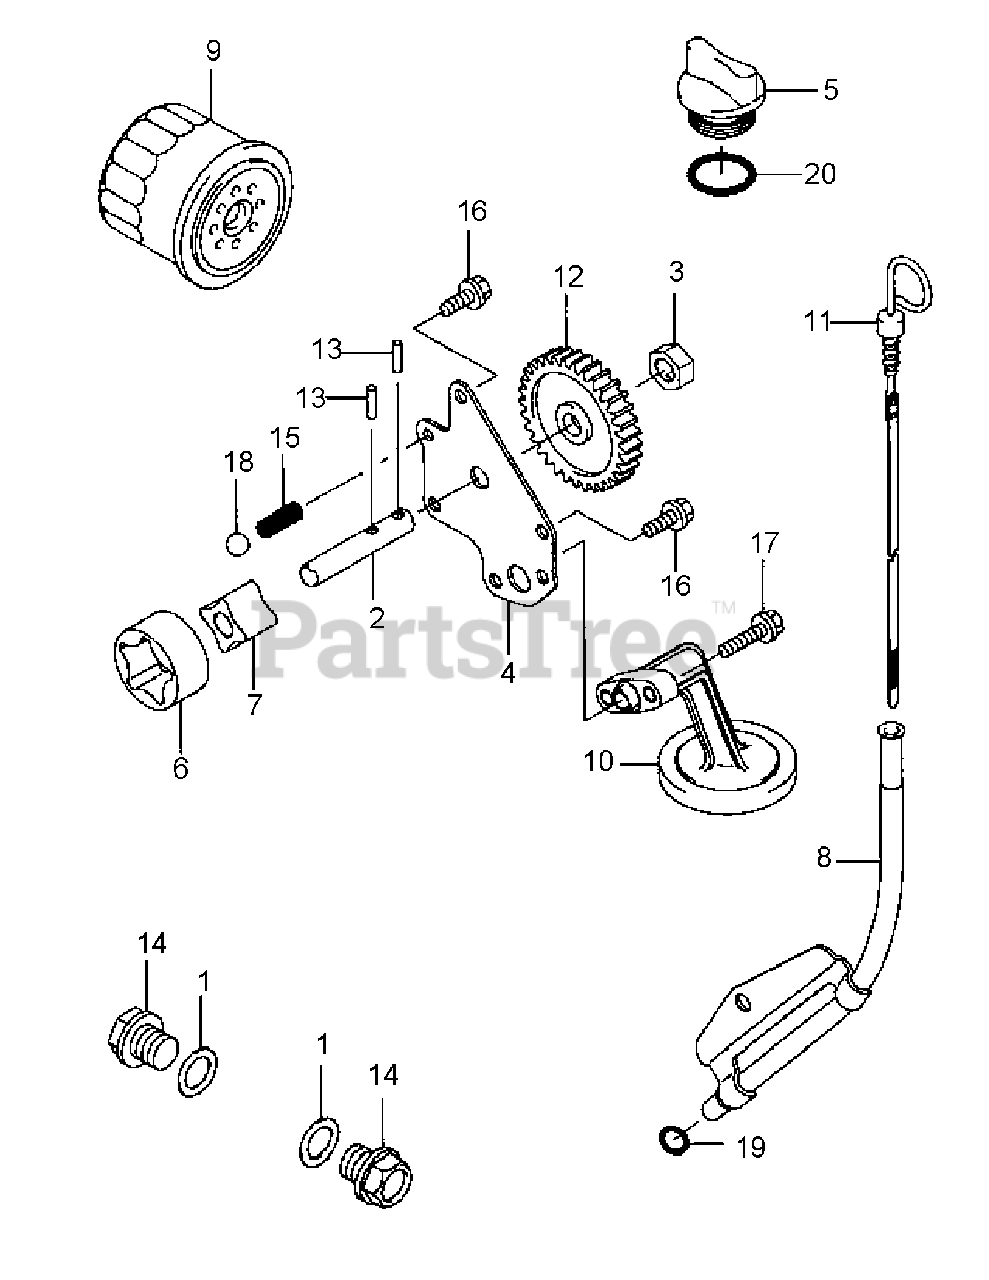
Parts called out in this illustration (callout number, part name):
1	DRAIN PLUG GASKET
2	OIL PUMP SHAFT
3	OIL PUMP HOLDER
4	OIL PUMP COVER
5	OIL FILLER CAP
6	OUTER PUMP ROTOR
7	INNER PUMP ROTOR
8	OIL GAUGE PIPE
9	OIL FILTER
12	SPUR GEAR 33T
16	FLANGED BOLT
17	FLANGED BOLT
19	O-RING 10mm
20	O-RING 25mm
